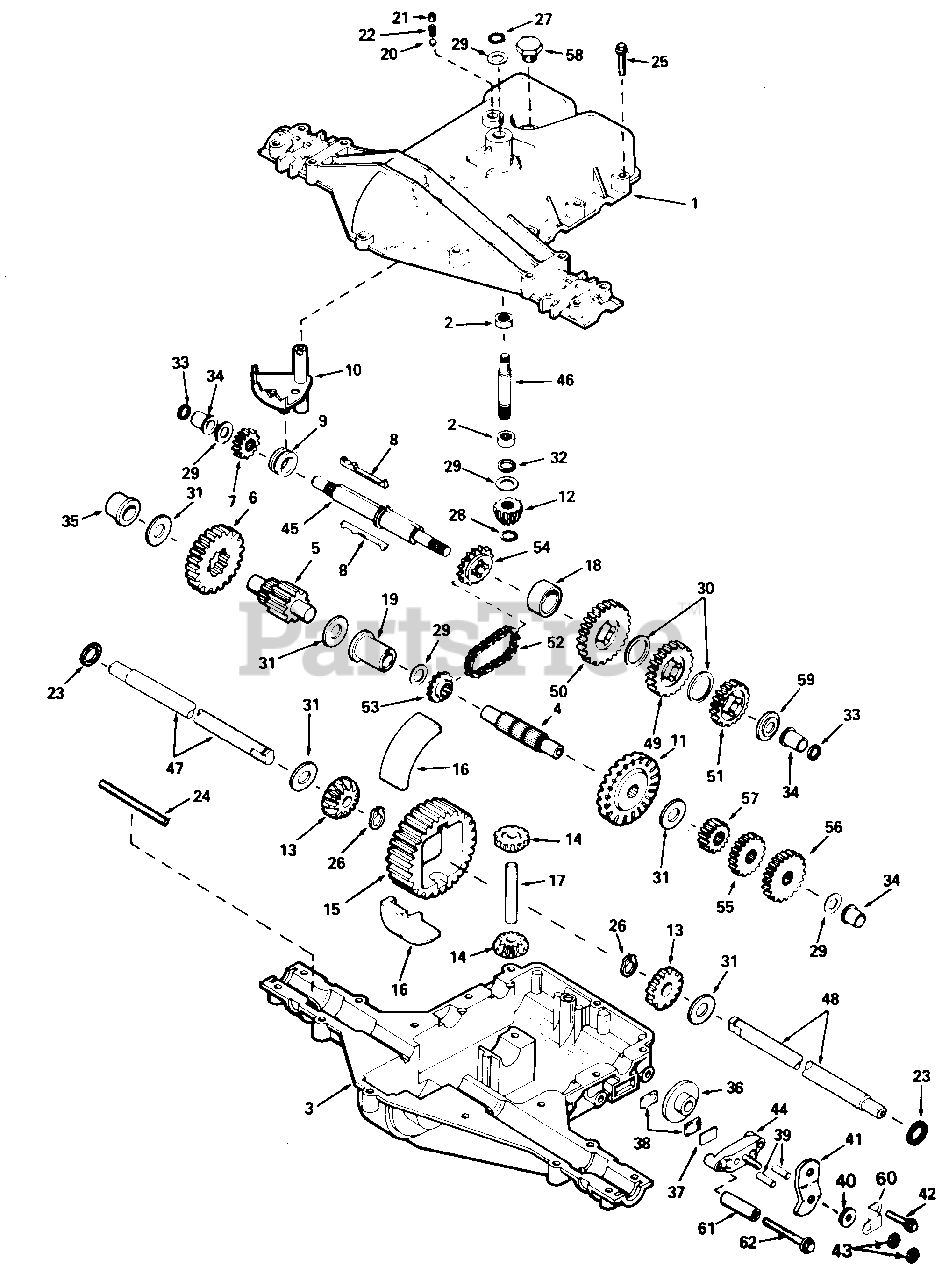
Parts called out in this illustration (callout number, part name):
1	Cover, Transaxle
2	Bearing, Needle
3	Case, Transaxle
4	Shaft, Counter
5	Shaft & Pinion Ass'y., Output
6	Gear, Output
7	Gear, Spur (15 Teeth)
9	Collar, Shifter
10	Rod & Fork Ass'y., Shift
11	Gear, Bevel (42 Teeth)
12	Bevel Pinion, Input
13	Gear, Bevel
14	Gear, Bevel Pinion
15	Gear, Ring
16	Block, Bearing
17	Pin, Drive
18	Spacer
19	Bushing, Flanged
20	Ball, Steel (5/16" Dia.)
21	Set Screw, 3/8-16 x 3/8
22	Spring
23	Ring, Felt
24	Packing, Felt
25	Screw, Flanged Hex Hd. Thd. Forming, 1/4-20 x 1-1/4
26	Ring, Retainer
27	Ring, Retainer
28	Ring, Retainer
29	Washer, Thrust
30	Washer, Thrust
31	Washer
32	"O" Ring
33	Seal, Square Cut
34	Bushing, Flanged
35	Bushing, Flanged
36	Disk, Brake
37	Plate, Brake Pad
38	Pad, Brake
39	Pin, Dowel
40	Washer, Flat
41	Lever, Brake
42	Screw, Flanged Hex Hd. Thd. Forming, 1/4-20 x 1-1/4
43	Nut, Lock, 5/16-24
44	Holder, Brake Pad
45	Shaft, Brake
46	Shaft, Input
47	Axle (12-1/2" Lg.)
48	Axle (15-3/8" Lg.)
49	Gear, Spur (25 Teeth)
50	Gear, Spur (35 Teeth)
51	Gear, Spur (20 Teeth)
52	Chain, Roller (No. 41 Chain, 24 Links)
53	Sprocket (9 Teeth)
54	Sprocket (18 Teeth)
55	Gear, Spur (25 Teeth)
56	Gear, Spur (30 Teeth)
57	Gear, Spur (15 Teeth)
58	Plug, Hex Hd., 9/16-18 Thd.
59	Washer, Thrust
60	Bracket
61	Spacer
62	Screw, Flanged Hex Hd. Thd. Forming, 1/4-20 x 2-1/4
